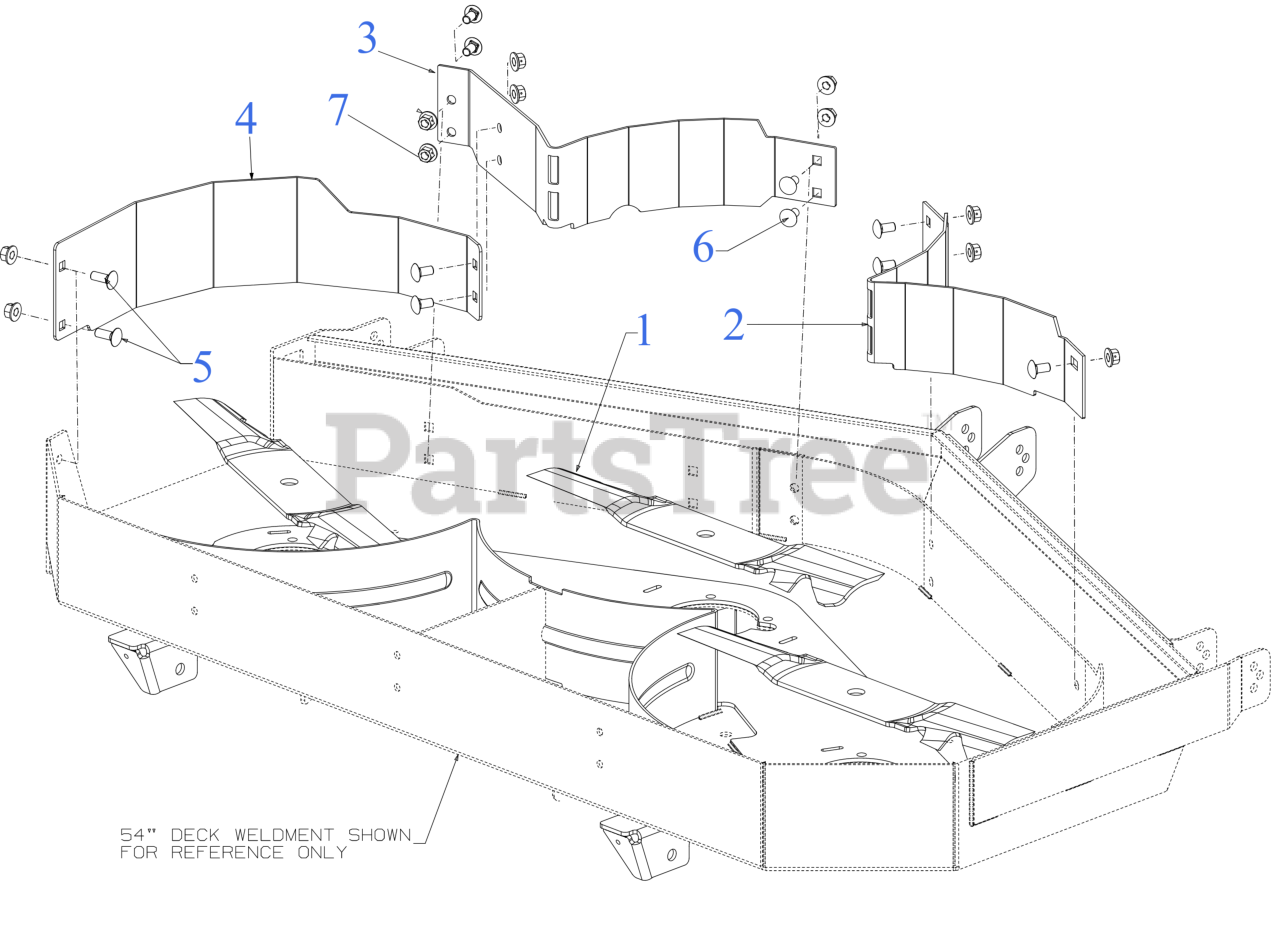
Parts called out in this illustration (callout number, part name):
1	19" XTREME BLADE
2	MULCH BAFFLE (LEFT)
3	MULCH BAFFLE (CENTER)
5	CARRIAGE BOLT 3/8-16 x 1.00 GR5
6	CARRIAGE BOLT 3/8-16 x .75
7	NUT-CTRLCK FLG HEX
